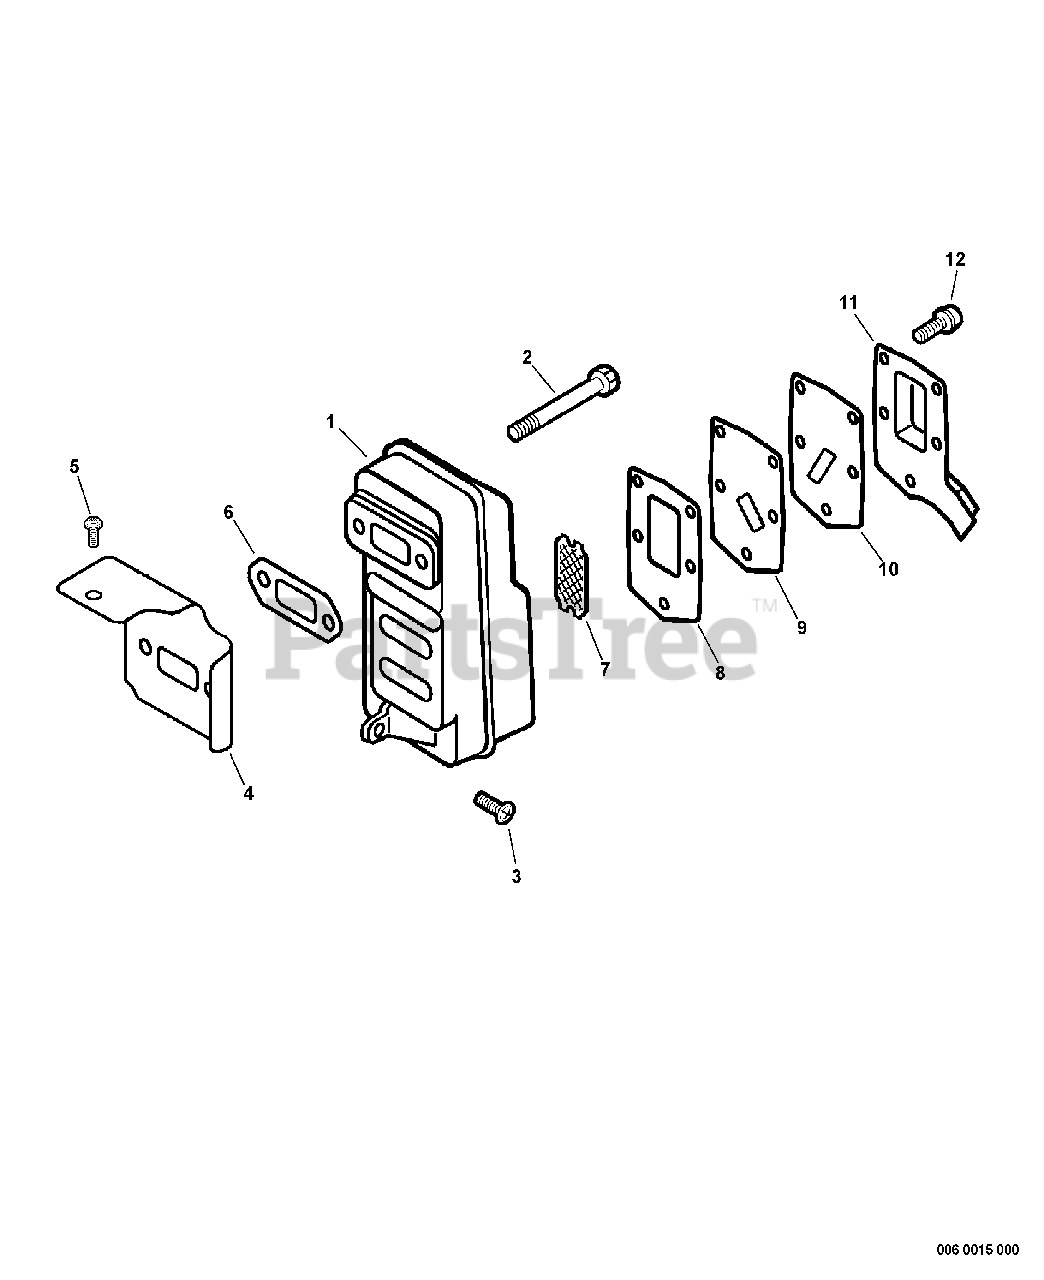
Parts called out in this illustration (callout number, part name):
1	MUFFLER
2	SCREW - 6X20
3	SCREW - 5X20
4	COVER, CYLINDER - EXHAUST
5	SCREW - 5X10
6	GASKET, EXHAUST
7	SCREEN, SPARK ARRESTOR
8	GASKET, EXHAUST
9	GASKET, EXHAUST
10	GASKET, EXHAUST
11	GUIDE, EXHAUST
12	SCREW - 4X14
